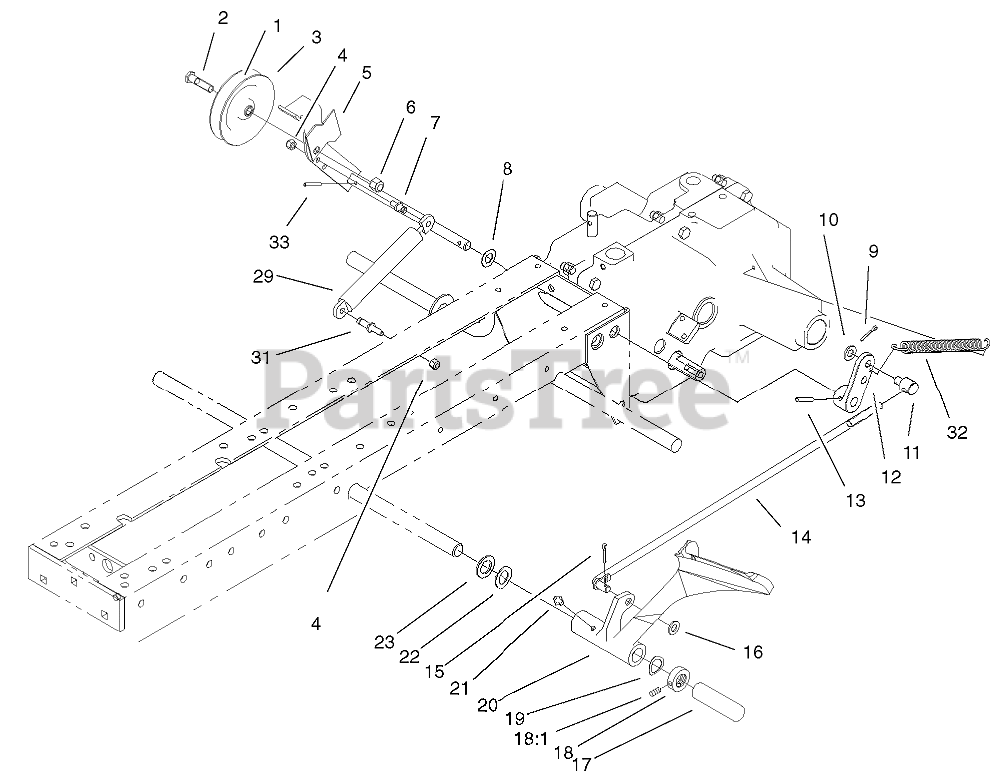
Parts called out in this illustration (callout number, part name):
1	BELT-V IN
2	BOLT-SPECIAL HEX
3	PULLEY-V, IDLER
4	NUT-LOCK, NI
5	IDLR ARM ASM
6	NUT-HEX
7	PIN-DAMPER, CLUTCH ARM
8	SHIM-WASHER
9	PIN-COTTER
10	WASHER-FLAT
11	TRUNNION
12	ARM-CLUTCH ROD
13	PIN-SPIROL
14	ROD AND GUIDE ASM
15	PIN-COTTER
16	WASHER-NYLON
17	SLEEVE-PROTECTIVE
18	COLLAR
18:1	SCREW-HSH
19	WASHER-BOWED
20	PEDAL-BRAKE, CLUTCH
21	FITTING-GREASE
22	WASHER
23	WASHER
29	DAMPER-GAS
31	PIN-DAMPER, CLASSIC FRAME
32	SPRING-CLUTCH
33	PIN-SPIROL
